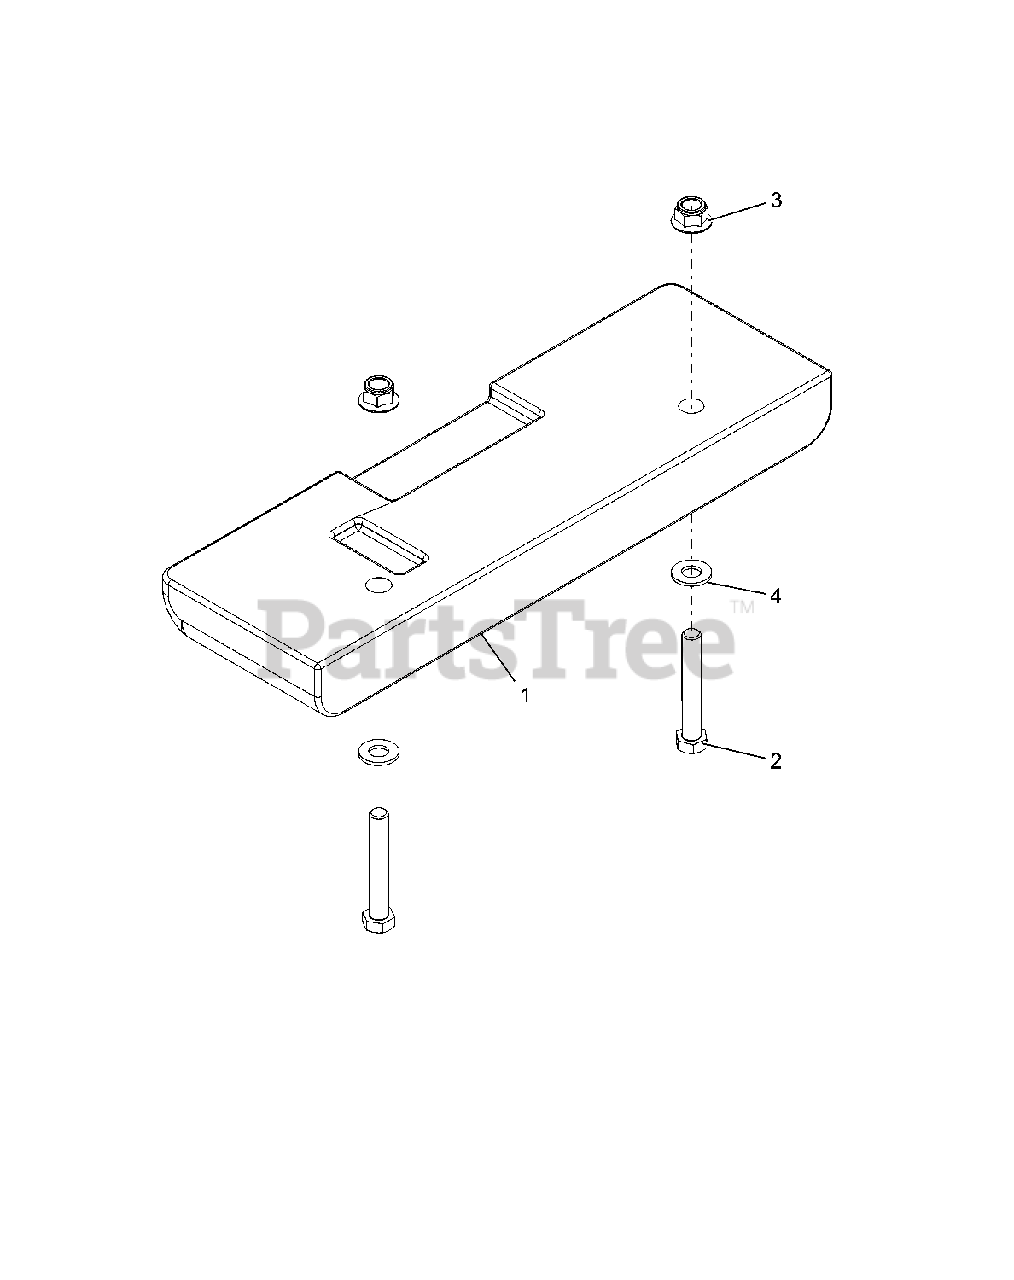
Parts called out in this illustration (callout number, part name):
1	WEIGHT, CAST IRON
2	BLT-HEX .50-13X3.25 GR5 YWZC
3	NUT-LK-NYL-FLG .50-13 YWZC
4	WSHR-FL-STL.531X1.06X.095YWZC
